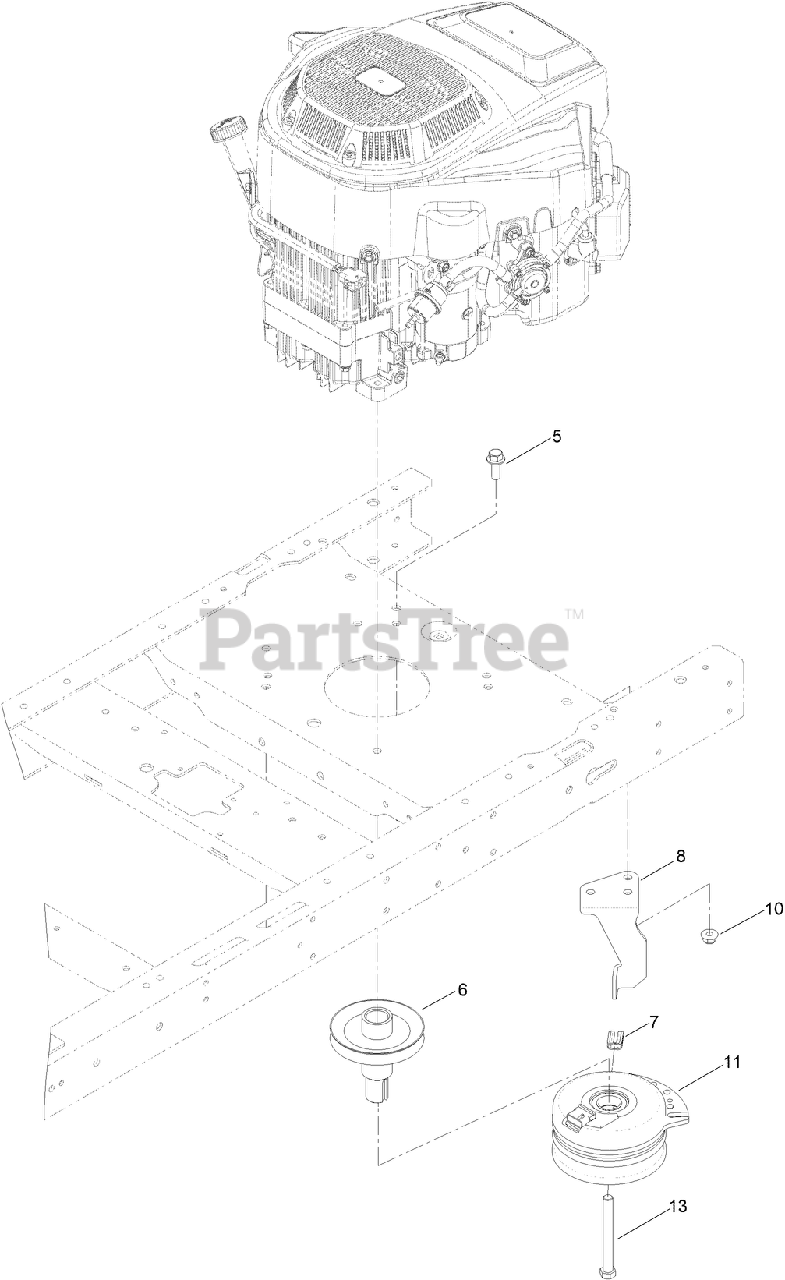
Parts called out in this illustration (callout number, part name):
5	SCREW-HHF
6	PULLEY-ENGINE
7	ISOLATOR-CLUTCH
8	STOP-CLUTCH (NARROW)
10	NUT-HF, NI
11	CLUTCH-ELECTRIC
13	SCREW-HH
